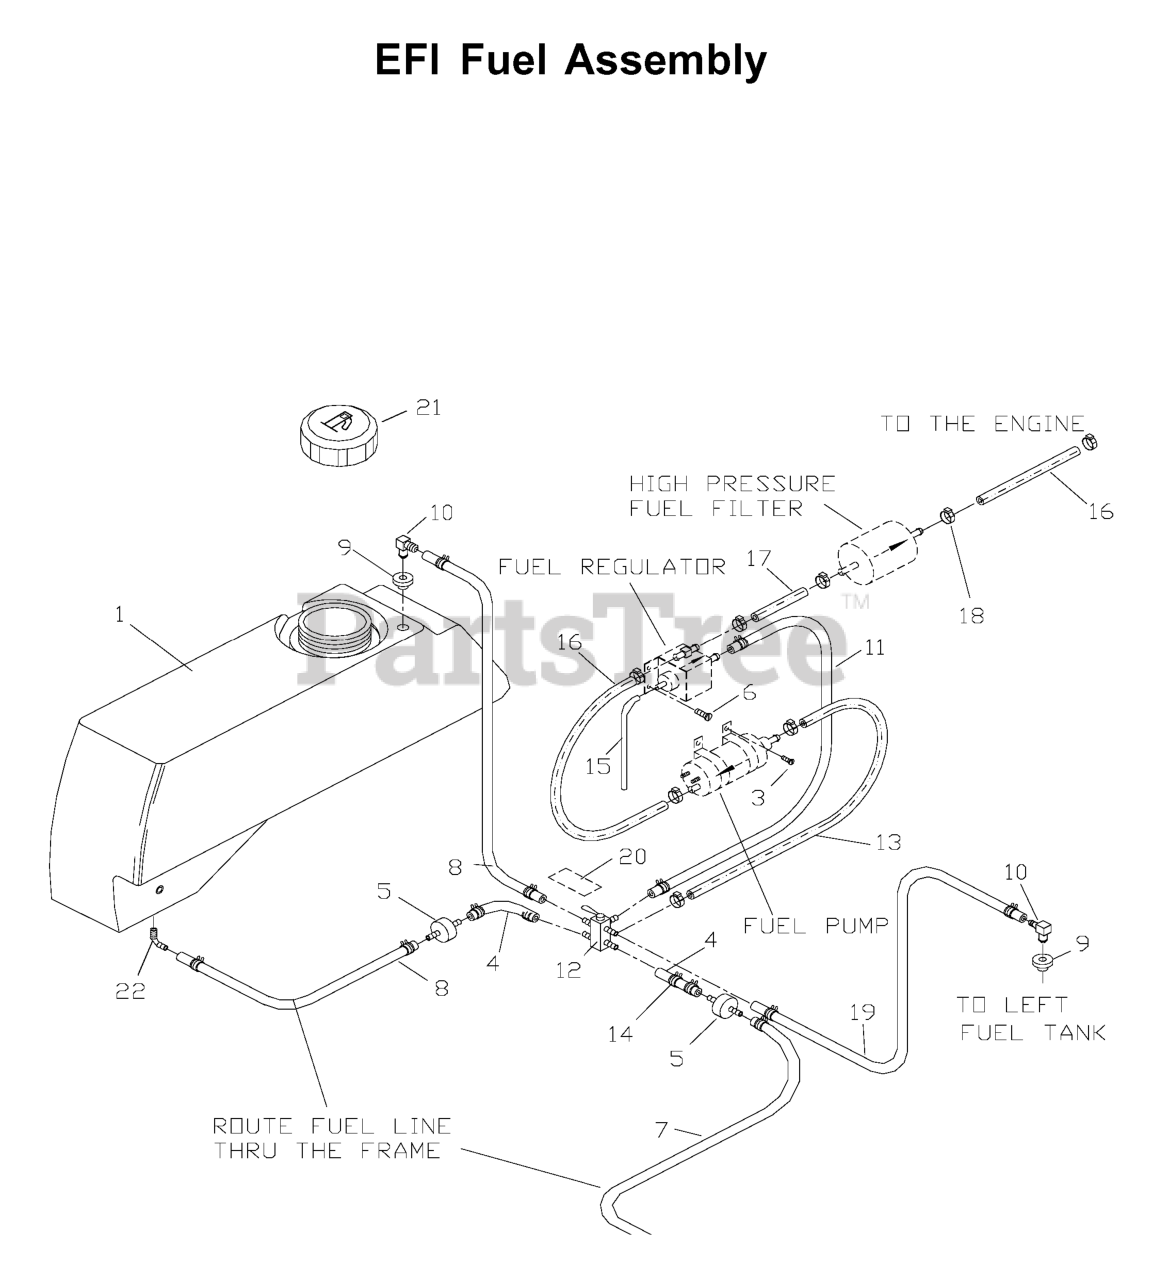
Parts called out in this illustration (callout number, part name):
1	FUEL TANK DIESEL RT
2	FUEL TANK DIESEL LT
3	SCREW #10 X 1/2 SELF TAPPING
4	GAS LINE 3 1/2"
5	FUEL FILTER
6	HEX CAP SCREW 1/4
7	FUEL LINE 29.5"
8	FUEL LINE 18"
9	RUBBER GROMMET
11	FUEL LINE 24"
12	FUEL VALVE
13	EFI HOSE - 18"
14	HOSE CLAMP
16	EFI HOSE - 8"
17	EFI HOSE - 4"
19	FUEL LINE 34"
20	FUEL VALVE DECAL
21	FUEL CAP ANTI-SPLASH
22	HOSE BARB 90 DEGREE
